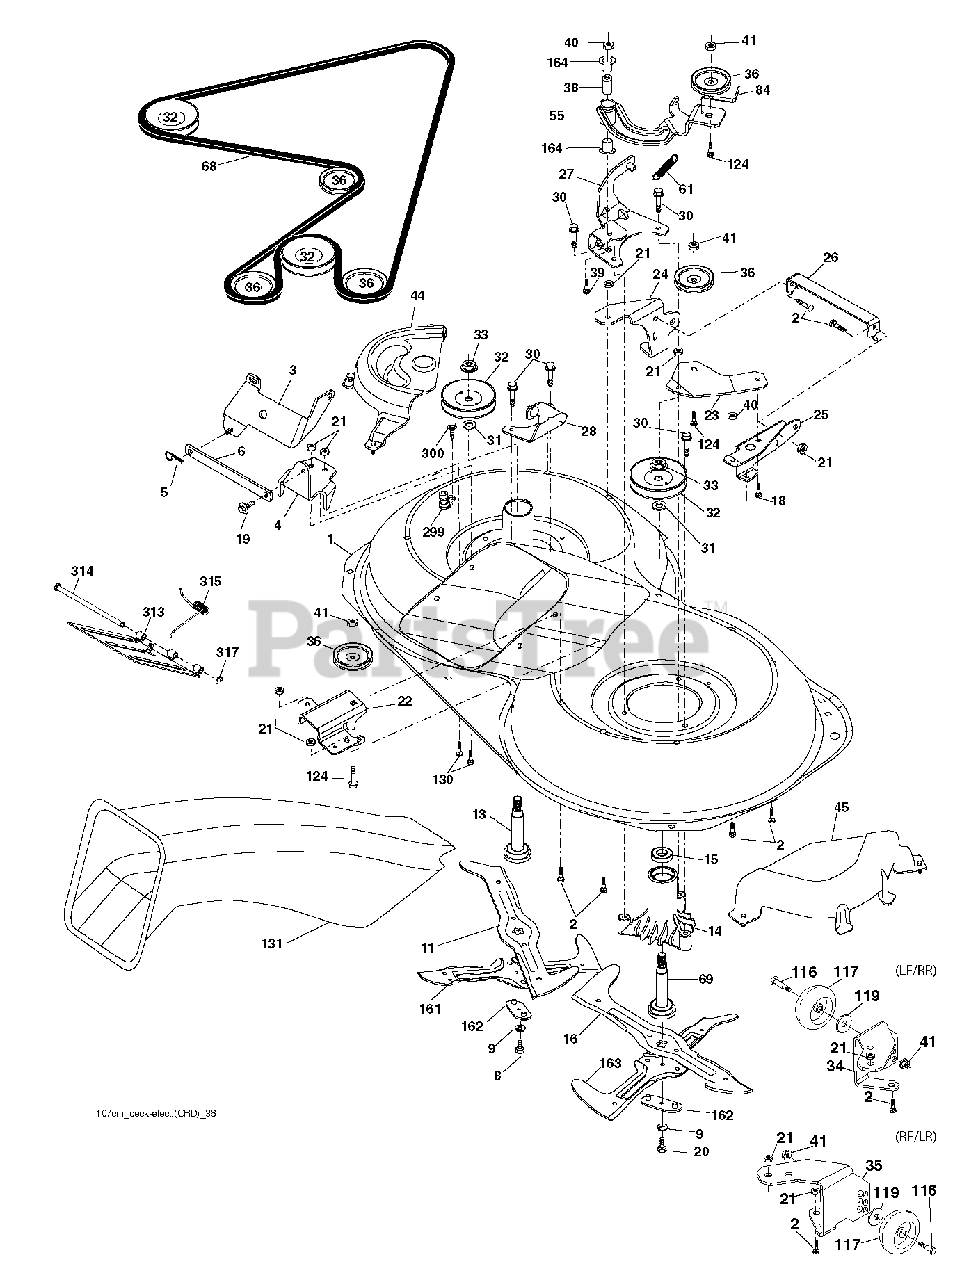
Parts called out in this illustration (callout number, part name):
2	BOLT
3	BRACKET.ASM.BAR.SWAY.CHASS
5	RETAINER-SPRNG RB
6	BAR SWAY
9	LOCKWASHER
11	BLADE.3N1.LH.CRD
13	SHAFT ASM VENT
14	HSG MANDREL
16	BLADE.3N1.RH.CRD
18	BOLT
19	BOLT SHD 5/16-18
21	LOCKNUT
22	BRACKET
23	BRACKET
27	BRACKET
30	SCREW, WASHER HEAD
31	WASHER.SPACER.MANDREL
33	NUT.FLANGE.LOCK.TOP
36	PULLEY.IDLER.4.25
40	LOCKNUT
41	NUT LOCK FLG 3/8-16 UNC
55	ARM IDLER
68	HEX-BELT 107 MOWER
69	SHAFT.ASM.W/LWR.BRG.RH.THREAD
84	KEEPER, BELT IDLER
116	BOLT.SHOULDER.3/8-16X3-5/8
117	WHEEL. GUAGE RALLY
124	BOLT.3/8-16X1.50
164	BRNG T
299	PORT.WASHOUT
317	E-RING.5/16"
